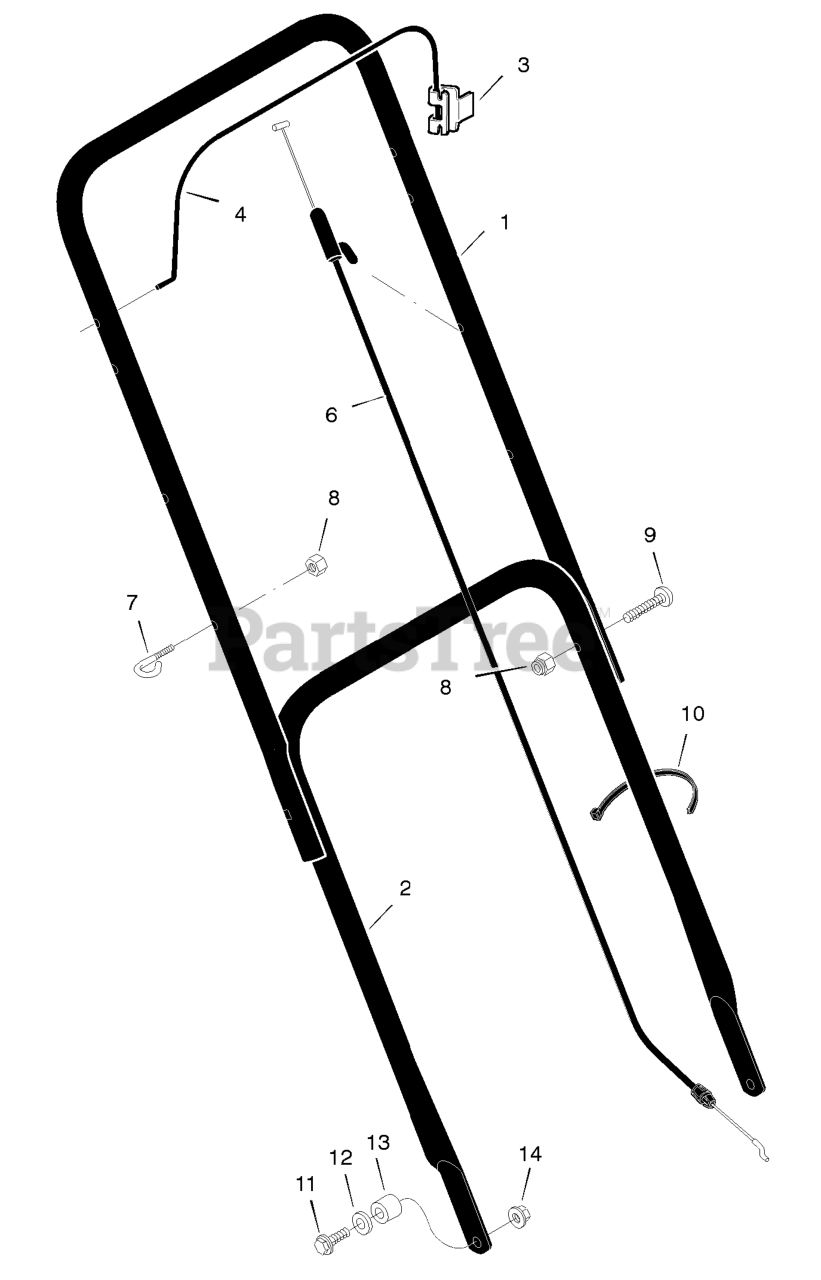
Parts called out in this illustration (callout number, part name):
1	Handle, Upper (Black)
2	Handle, Lower (Black)
3	Bracket, Stop Lever
4	Lever, Stop
6	Engine Stop Cable
7	GUIDE, ROPE
8	Locknut
10	Fastener, Cable
11	Bolt
14	Nut
